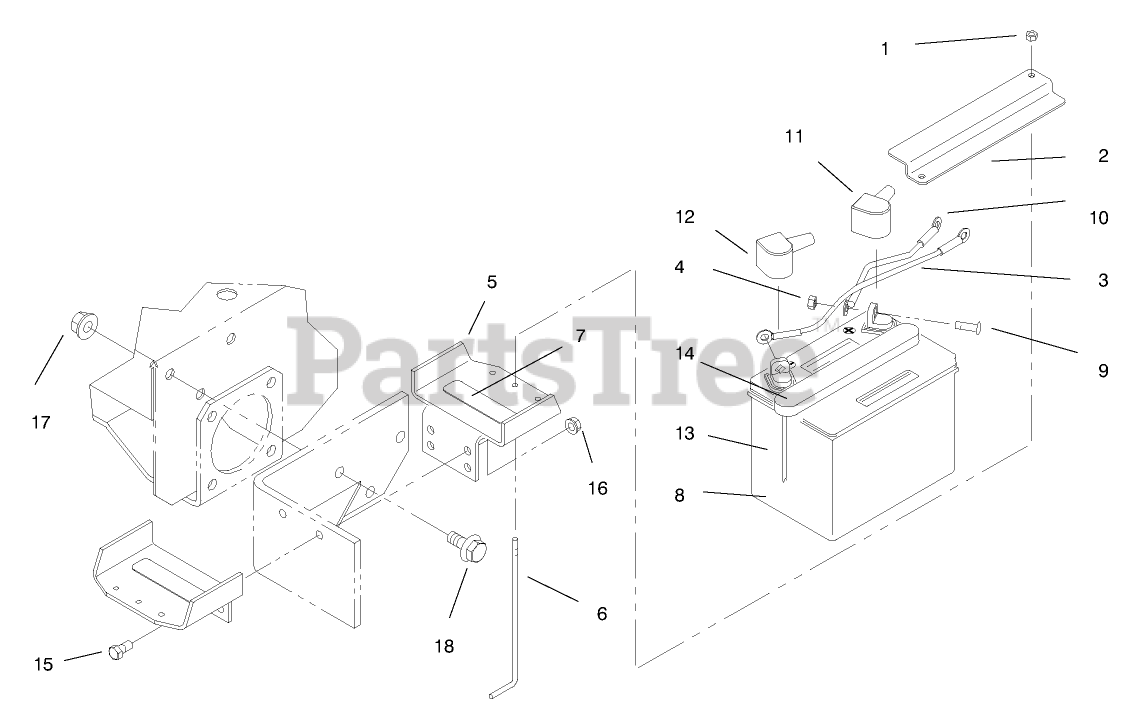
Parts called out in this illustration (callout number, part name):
1	NUT-LOCK, NI
2	STRAP - BATTERY
3	CABLE
4	NUT-KEPS
5	HOLDER-BATTERY
6	ROD-SUPPORT, BATTERY
7	PAD-TANK, FUEL
8	Battery
9	SCREW-HH
10	WIRE ASM
11	BOOT-TERMINAL, RED
12	BOOT-TERMINAL, BLACK
13	TUBE-VENT
15	SCREW-HH
16	NUT-LOCK, NI
17	NUT-HF
18	SCREW-HHF
